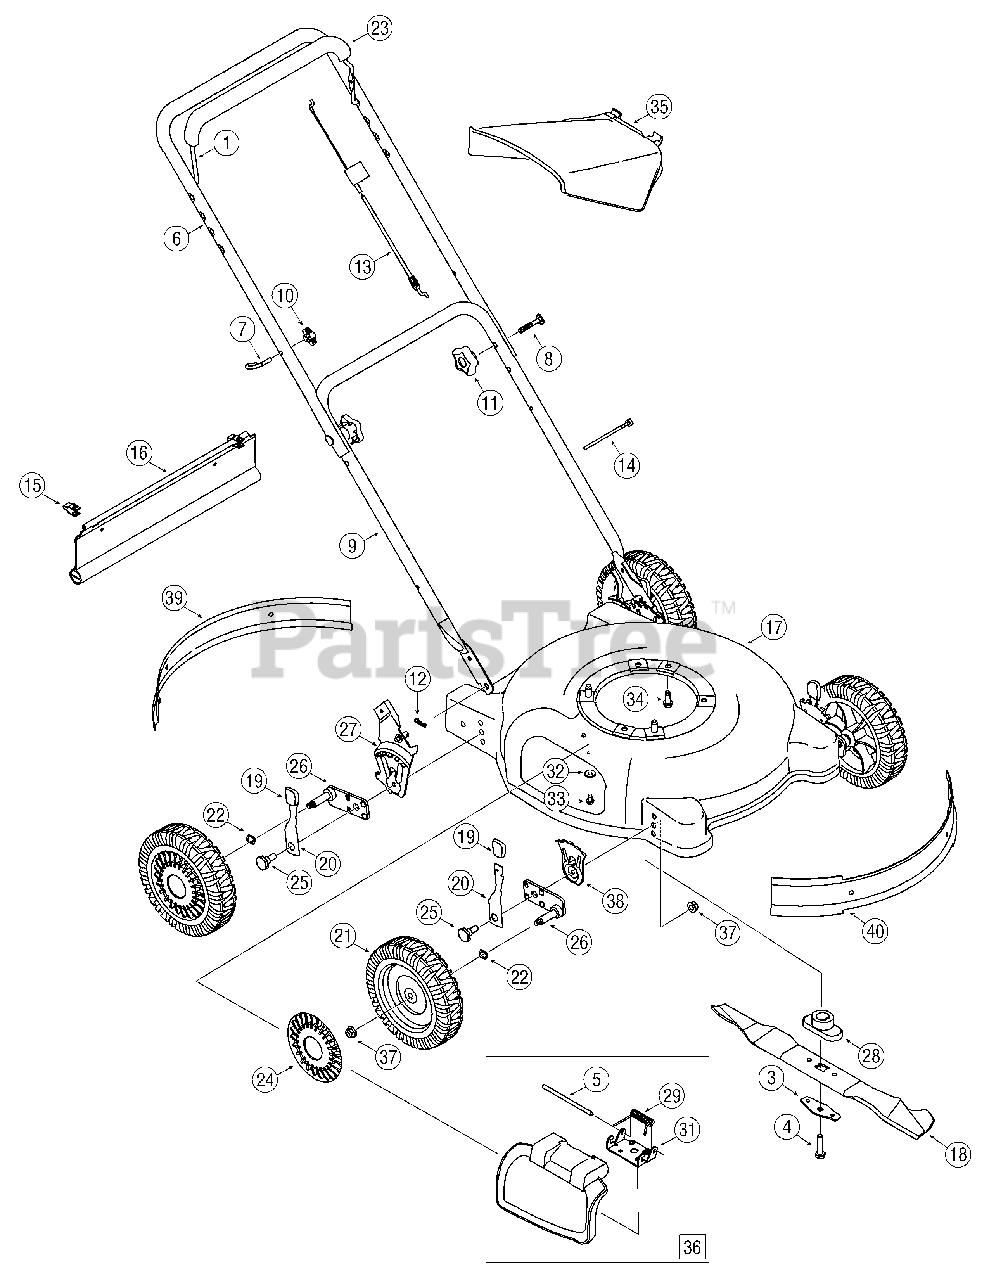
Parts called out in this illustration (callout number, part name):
2	Saddle Washer
3	Blade Bell Support
5	Hinge Pin
8	Carriage Bolt
11	Star Knob
12	Hairpin Clip
13	Control Cable 48.25"
14	Cable Tie
15	Hinge Clip
19	Height Adjustment Knob
20	Spring Lever
21	Wheel Assembly
22	Wave Washer
23	Snap-On Bail Cover
24	Hubcap: Radial Spoke Gray
25	Shoulder Bolt
26	Rear Pivot Arm Assembly - RH
26	Rear Pivot Arm Assembly - LH
26	Front Pivot Arm Assembly - RH
26	Front Pivot Arm Assembly - LH
29	Torsion Spring
30	Height Adjust. Assembly LH
30	Height Adjust. Assembly RH
33	Hex Washer Hd. TT Screw
34	TT Sems Screw
35	Chute Deflector
36	Mulching Plug Assembly
38	Height Adjustment Plate
